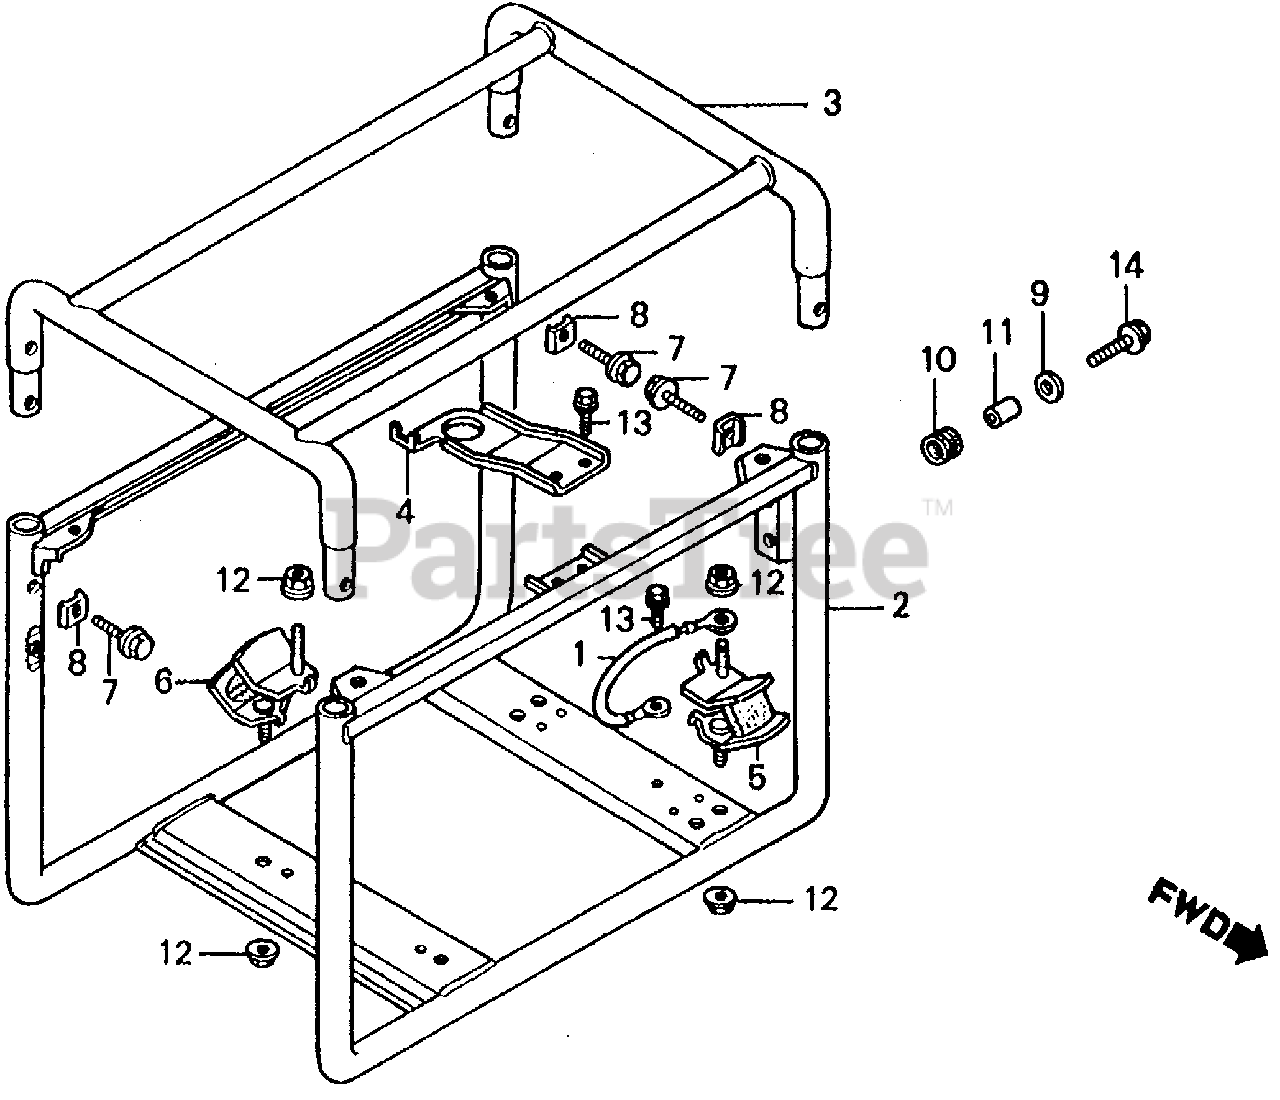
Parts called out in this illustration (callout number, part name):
1	CABLE, GROUND
2	FRAME (LOWER)
3	FRAME (UPPER)
4	STAY, BUMP STOP
5	RUBBER, FR. (LOWER)
6	RUBBER, RR. (LOWER)
7	BOLT, FLANGE (8X20)
8	WASHER, FRAME JOINT
9	WASHER, FLAT (20MM)
10	RUBBER, CONTROL BOX
11	COLLAR, CONTROL BOX
12	NUT, FLANGE (8MM)
13	BOLT, FLANGE (6X10)
14	BOLT, FLANGE (6X18)
